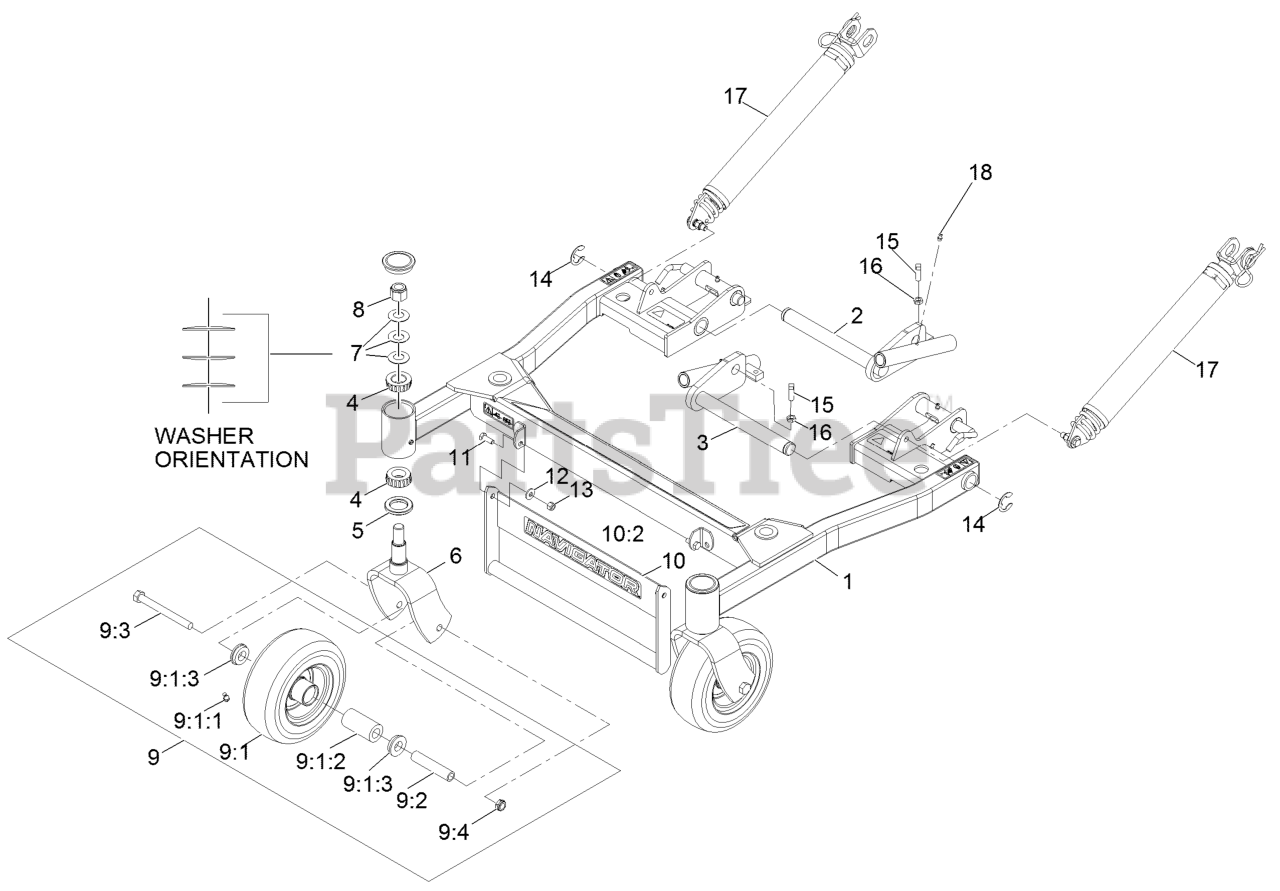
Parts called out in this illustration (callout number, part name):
1	DECK SUPPORT ASM
2	PIVOT-DECK, RH
3	PIVOT-DECK, LH
4	Cone-Bearing Tapered Roller
5	SEAL-GREASE
6	FORK-CASTER
7	WASHER-BELLVILLE
8	NUT-LOCK, NI
9	ASM,FF CASTER WHEEL W/AXL
9:1	ASM,WHEEL,TIRE & BRGS 8X3
9:1:1	FITTING-GREASE
9:1:2	BEARING-ROLLER, STRAIGHT
9:1:3	BUSHING
9:2	SPACER-CASTER, FRONT
9:3	SCREW-HH
9:4	NUT-HEX
10	ASM,DECK LIFT HANDLE W/DE
10:2	Decal-Navigator Logo
11	SCREW-HH
12	WASHER-SPRING
13	NUT-LOCK, NI
14	RING-SNAP
15	SCREW-SET, SQH
16	NUT-JAM
17	LIFT ASSIST SPRING ASM
18	FITTING-GREASE
